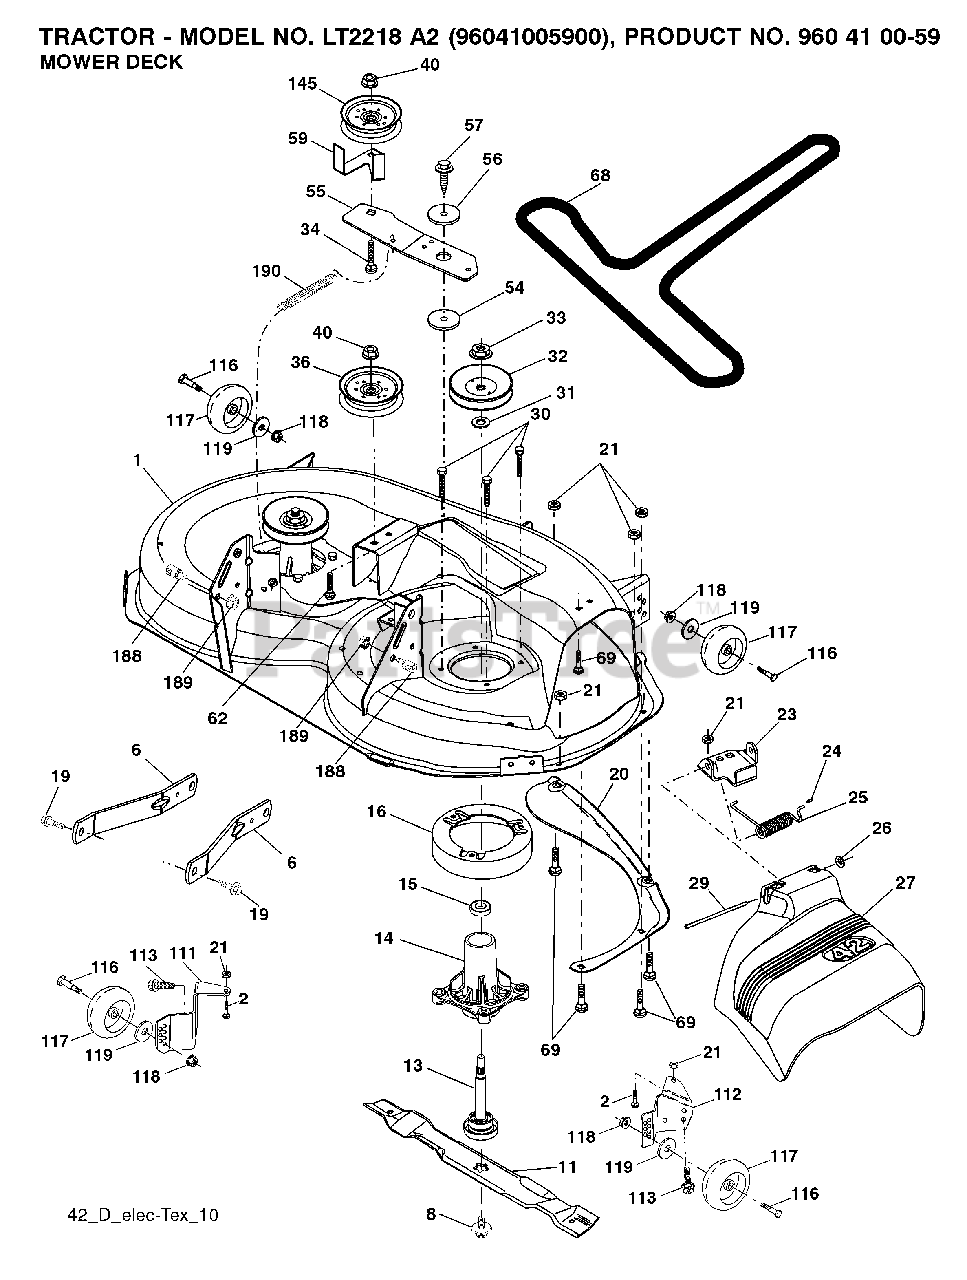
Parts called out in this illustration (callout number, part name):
1	DECK.WELDMENT.42"
2	BOLT
6	ARM.SUSPENSION.MOWER.R
8	BOLT.WASHER.ASM.7/16-2
11	42" HI-LIFT BLADE
13	SHAFT.ASM.MDRL.N/GREASE.38
14	HOUSING MANDREL
16	STRIPPER, MWR ROUND
19	BOLT.SHOULDER
20	BAFFLE.VORTEX
21	LOCKNUT
23	BRKT.DEFLECTOR.38"2005+
24	CAP-SLEEVE LT
25	SPRING.TORSION.DEFLECT
26	NUT PUSH M
27	SHIELD.DEFLECTOR.MOWER.42"BLAC
29	ROD.HINGE
30	SCREW, WASHER HEAD
31	WASHER.SPACER.MANDREL
32	PULLEY/MANDREL
33	NUT.FLANGE.LOCK.TOP
34	BOLT.3/8-16X1.50
36	PULLEY.IDLER.2006
40	NUT LOCK FLG 3/8-16 UNC
55	IDLER.ARM
56	SPACER.RETAINER
57	SCREW 3/8-16X1
59	GUARD, BELT
62	BOLT
68	BELT V SECONDARY
69	BOLT
111	BRKT.WHEEL.GAUGE.LH.42"
112	BRKT.WHEEL.GAUGE.RH.42"
113	BOLT.5/16HEX.WHS.HD
117	WHEEL.GAGE.HALF.SPOKED
118	LOCKNUT
119	WASHER
145	PULLEY.IDLER.48"PRIMARY
188	STUD.FASTNER.W/ANTI-ROTATE
189	NUT LOCK HEX FLANGE 5/16-18
190	SPRING.MOWER.DRIVE.ELECTRIC
